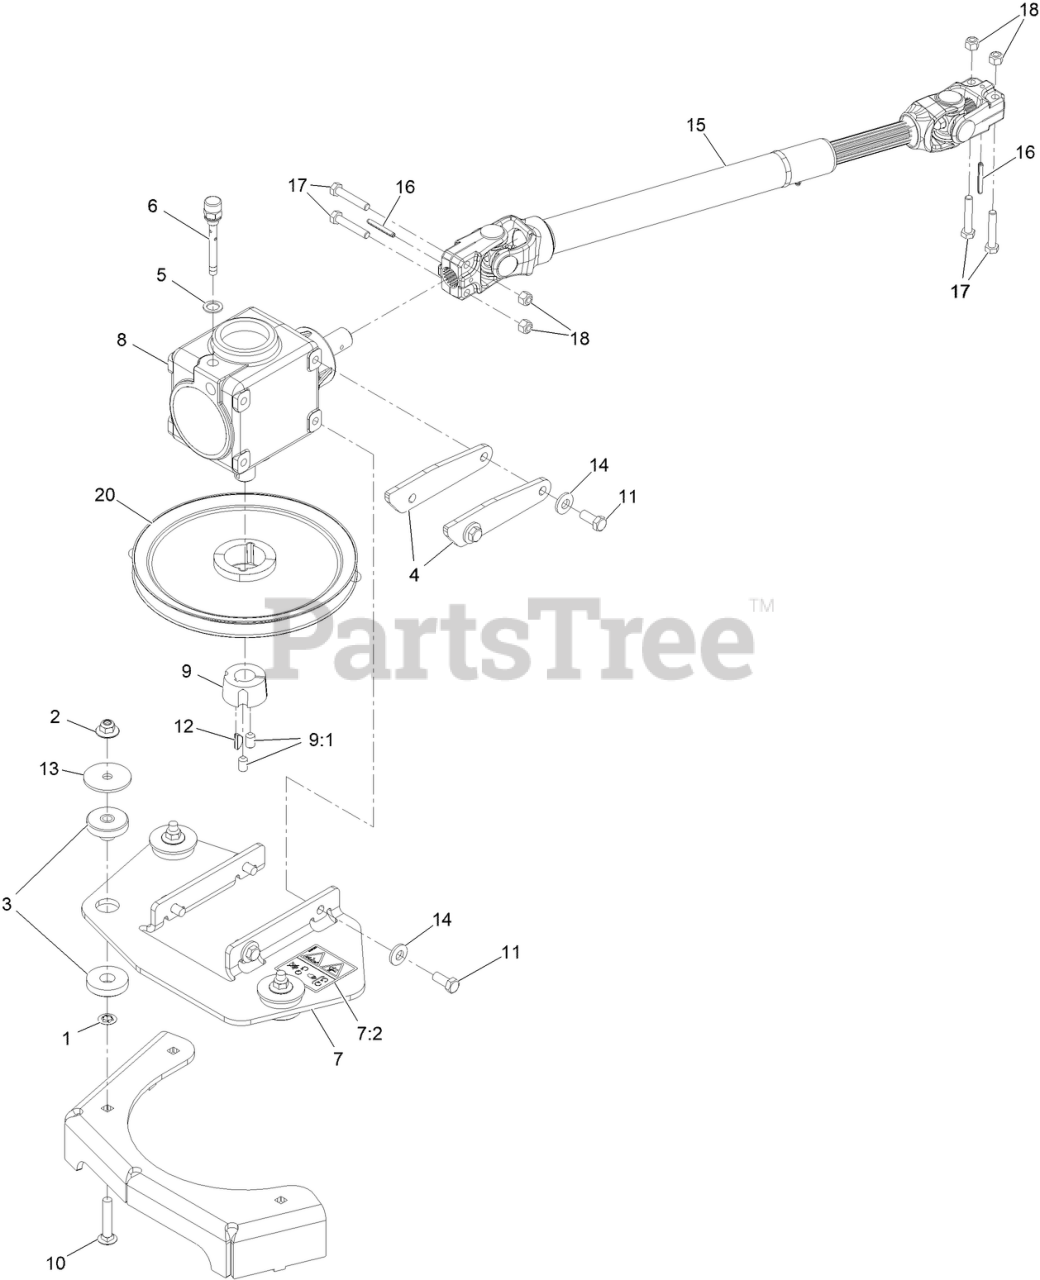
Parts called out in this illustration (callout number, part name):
1	NUT-PUSH
2	NUT-FLANGE, NI
3	MOUNT-ISO
4	STOP-GEARBOX
5	WASHER
6	PLUG-BREATHER
7	MOUNT-GEARBOX
7:2	DECAL-HAZARD, ENTANGLEMENT
8	GEARBOX ASM
9	BUSHING-TAPERLOCK
9:1	SCREW-SET
10	SCREW-CARR
11	SCREW-HH
12	KEY-WOODRUFF
13	WASHER-FLAT
14	WASHER-BELLEVILLE
15	DRIVESHAFT ASM
16	PIN-ROLL
17	SCREW-HH
18	NUT-LOCK, NI
20	PULLEY
